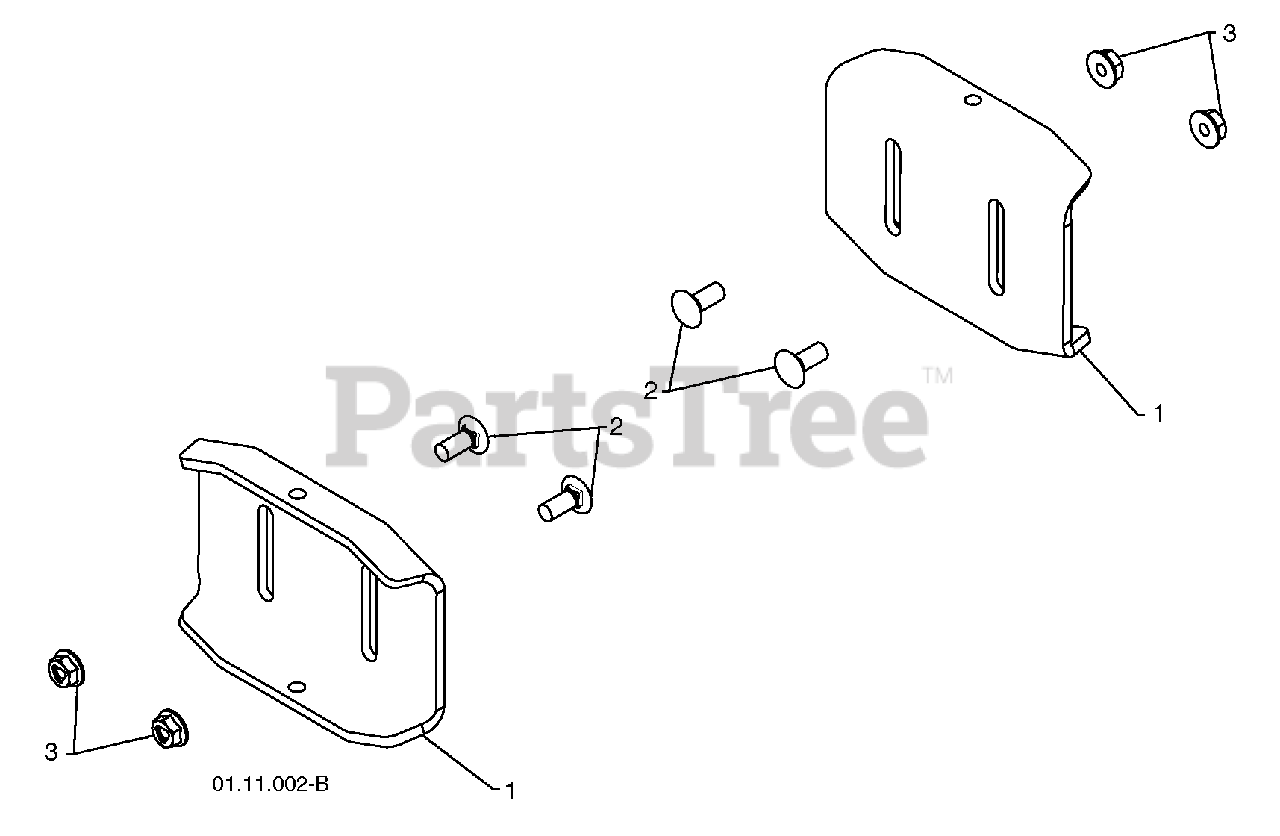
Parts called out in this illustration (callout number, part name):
1	SKID PLATE
2	CARRIAGE BOLT 5/16-18 X .750
3	NUT 5/16-18
